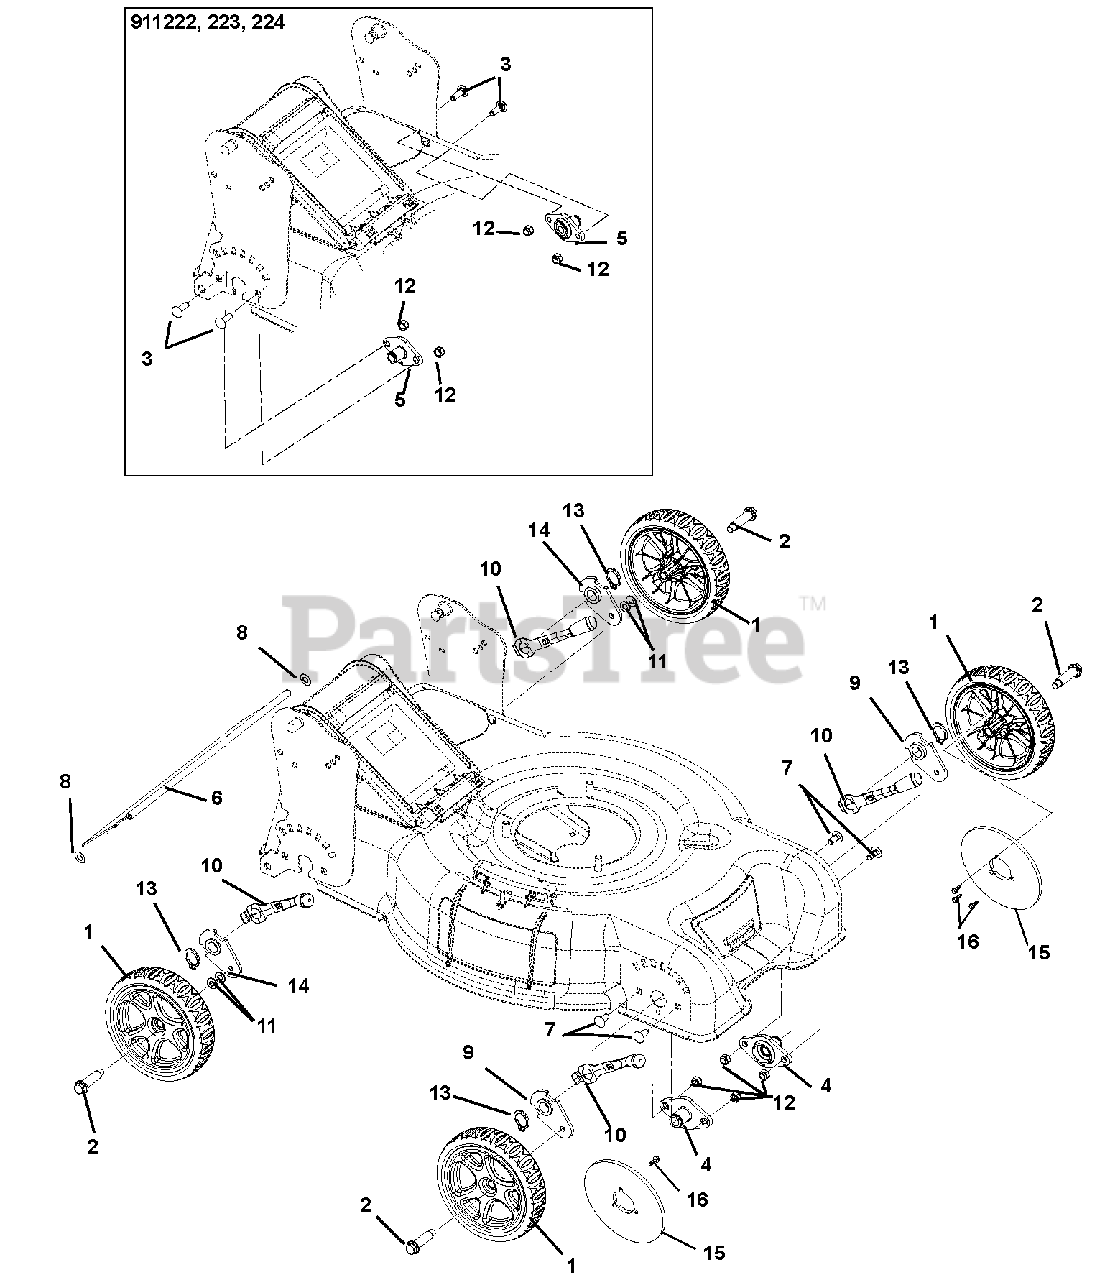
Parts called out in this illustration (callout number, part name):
1	Wheel, 8.5" WBLM Assembly
2	Bolt, Wheel Shoulder
3	Bolt, Round Head Square Neck .31-18 x 1.00 Grade 5
4	Wheel Mount Hub (911220, 221)
5	Wheel Mount Hub (911222, 223, 224)
6	Guard, WBLM
7	Bolt, Round Head Square Short Neck .31-18 x .75 Grade 5 (911220, 221)
8	Retainer, .38 Push-On
9	Plate, Front Wheel Mount
10	Height of Cut Lever
11	Washer, Flat Steel .406 x .812 x .065 (911222, 223, 224)
12	Nut, Locking Top Flange .31-18
13	Ring, Retaining - External .689 x .077
14	Plate, Rear Wheel Mount
15	Weight, Wheel (991224)
16	Screw-Tapping .25-15X.75 Hi-LO Hex Washer Head (991224)
